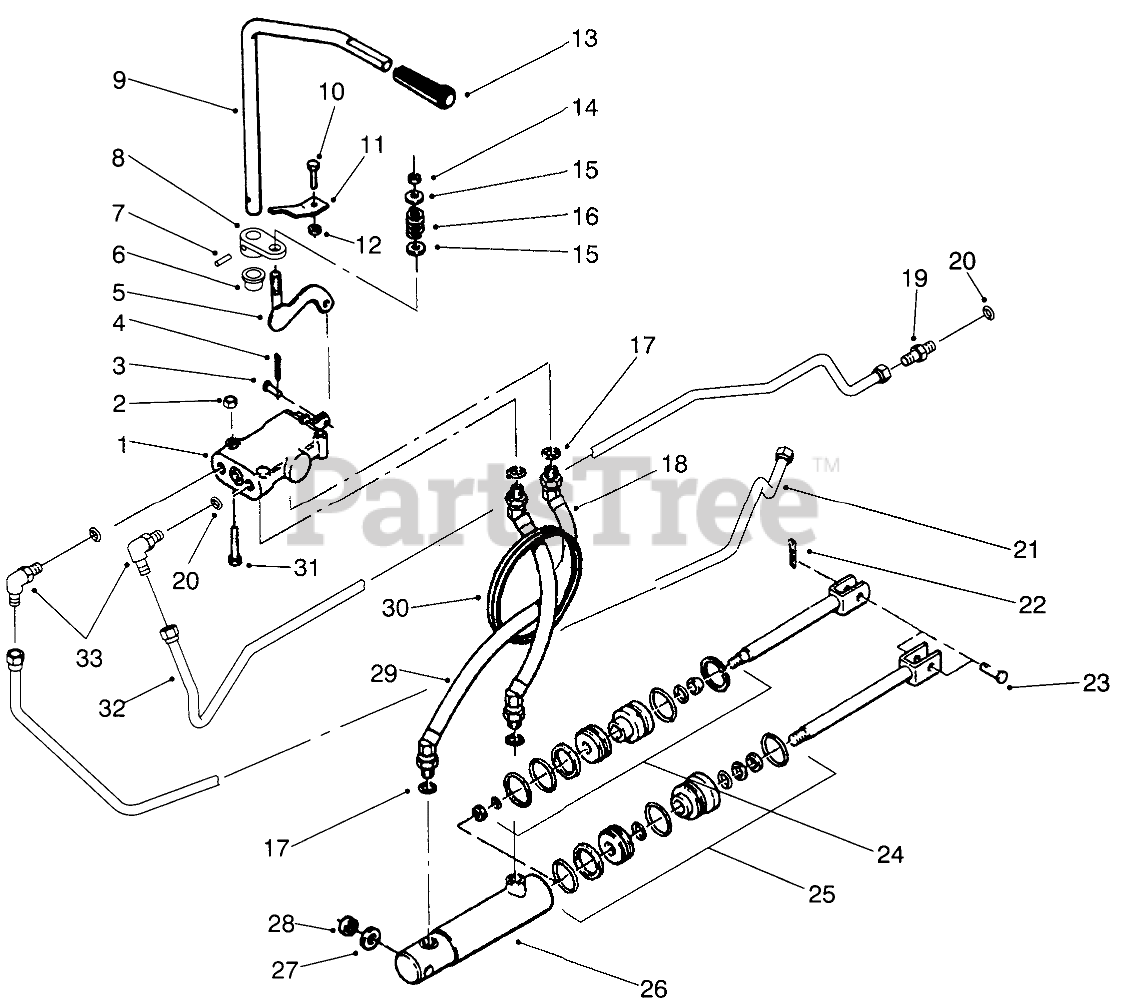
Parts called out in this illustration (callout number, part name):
1	Valve-Hydraulic(Incl.Ref.#3-4)
2	NUT-LOCK, NI
3	Pin
4	PIN-COTTER
5	WLDMT-LIFT BAR
6	NYLINER BUSHING
7	SPIROL PIN 7/32X7/8
8	ARM-CONTROL
9	ROD-LIFT CONTROL
10	SCREW-HH
11	BRACKET-CONTROL R B
12	NUT-LOCK, NI
13	KNOB-HYDRAULIC LIFT
14	NUT-LOCK, NI
15	WASHER-PLAIN
16	SPRING
17	O RING
18	Hose ASM-Hydraulic
19	Fitting-Straight Adapter (Incl. Ref. #20)
20	0-Ring
21	TUBE-HYD PRESSURE
22	PIN-COTTER
23	CLEVIS PIN
24	S/A O-RING&GASKET AS
25	S/A 108872 HYD CYL
26	Cylinder-Hydraulic (Incl. Ref.#24-25)
27	WASHER
28	SPACER-OUTER
29	Hose ASM-Hydraulic
30	GROMMET
31	SCREW-HH
32	TUBE-HYD RETURN
33	Fitting-90 (Incl. Ref. #20)
